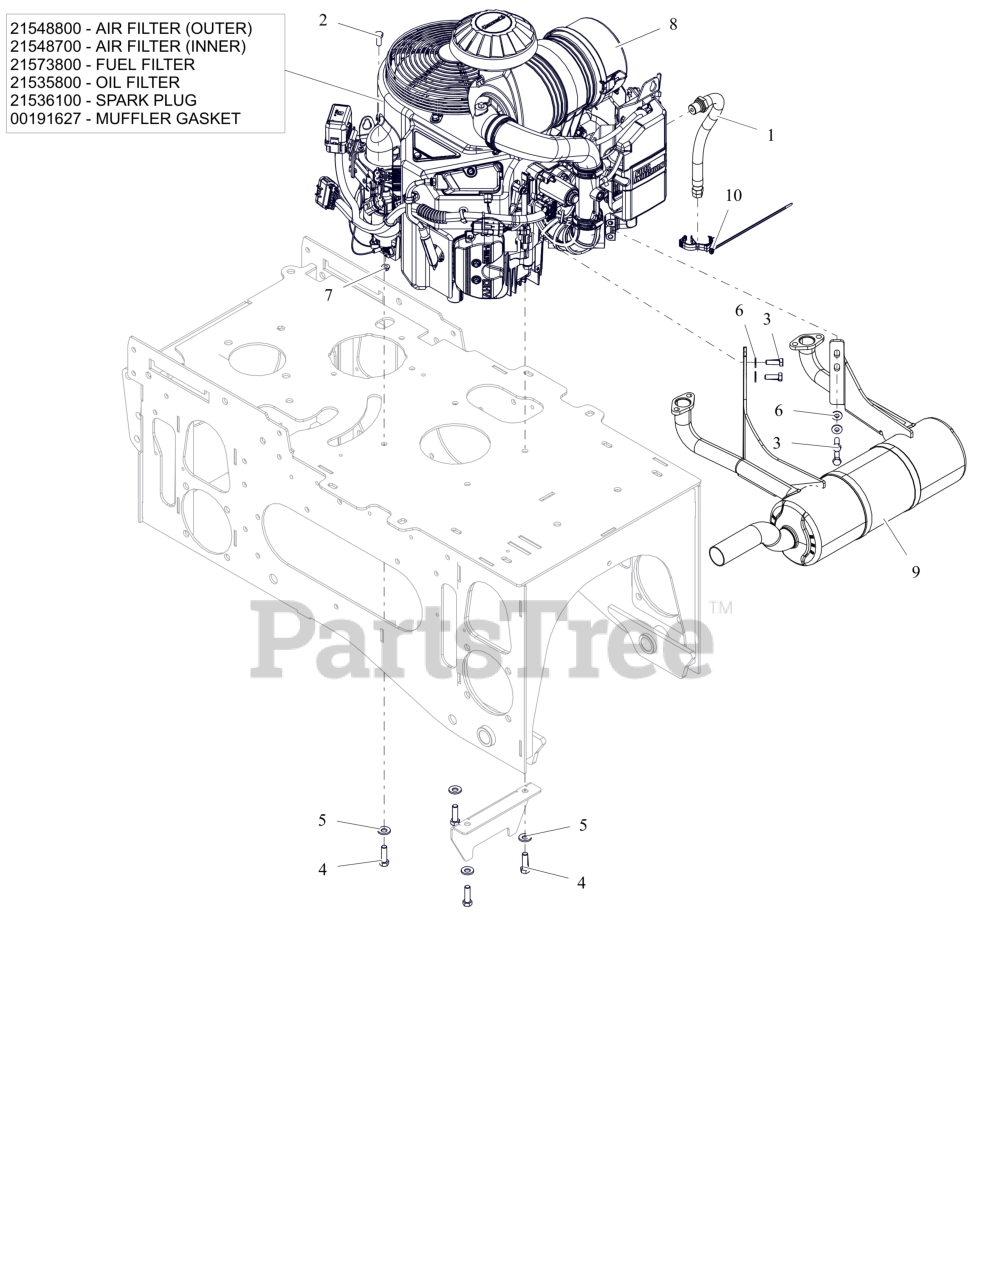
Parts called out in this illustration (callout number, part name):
1	HOSE, OIL DRAIN
2	BLT, HEX M8-1.25X20 G8.8 ZCC
3	BLT,HEX M8-1.25X25 G8.8 ZC120
4	BLT, HEX .38-16X1.25 G5 ZCC NT
5	WASHER, 3/8" SPRING DISC
6	WSHR, FLT .312X.734X.065 ZCC
7	NUT- SPNLK-FLG M6-1.0 G8.8 ZCC
8	ENGINE, KAWASAKI FX850 EFI
8	FILTER, OUTER
8	FILTER, INNER - KAW
8	FUEL FILTER-KAWASAKI FR
8	FILTER,OIL - KAW
8	PLUG, SPARK
8	GASKET, MUFFLER S/O
9	MUFFLER- W/BRACKETS- EES
10	CLIP- HARNESS CABLE TIE
